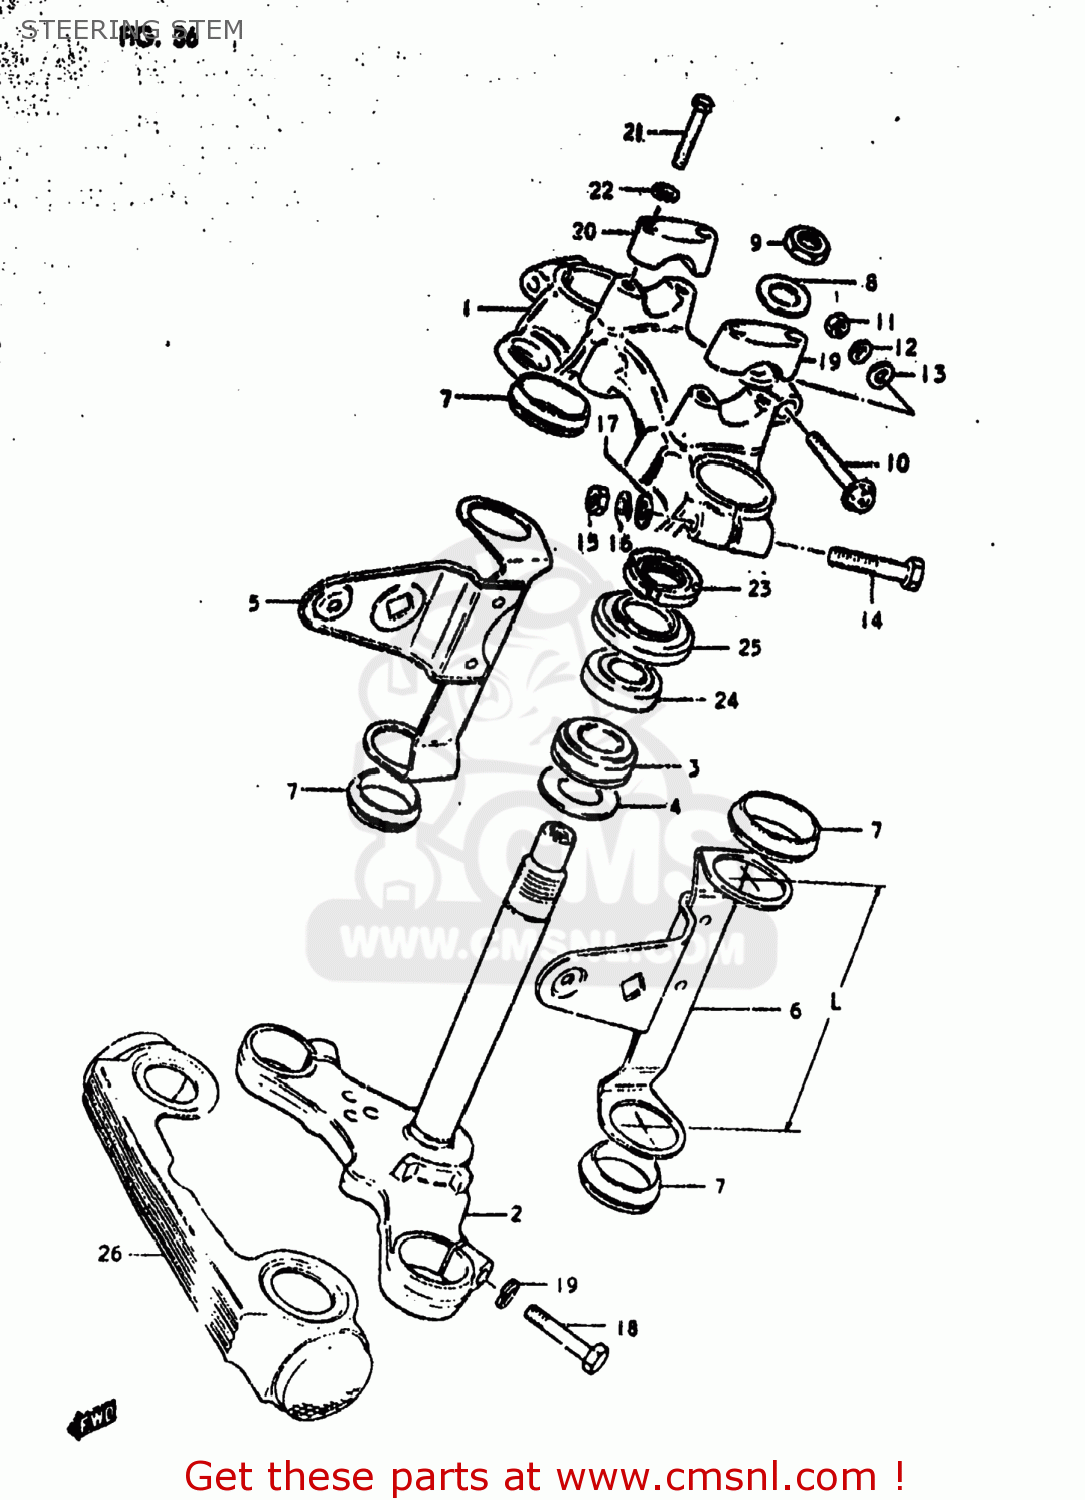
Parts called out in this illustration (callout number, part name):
1	HEAD,STEERING STEM
2	STEM,STEERING
3	BEARING
4	WASHER,THRUST
5	BRACKET,HEADLAMP,RIGHT
6	BRACKET,HEADLAMP,LEFT
7	CUSHION,HEADLAMP BRACKET
8	WASHER
9	NUT,FR FORK UPR BRACKET
10	BOLT
11	NUT
12	LOCK WASHER
13	WASHER
14	BOLT 10X55
15	NUT
16	LOCK WASHER
17	WASHER
18	BOLT 10X40
19	LOCK WASHER
20	HOLDER,HANDLE UPR
21	BOLT
22	LOCK WASHER
23	NUT,STEERING STEM(25X44X10)
24	TAPER,ROLLER BEARING
25	DUST SEAL,STEERING,UPPER
26	COVER,FR FORK
